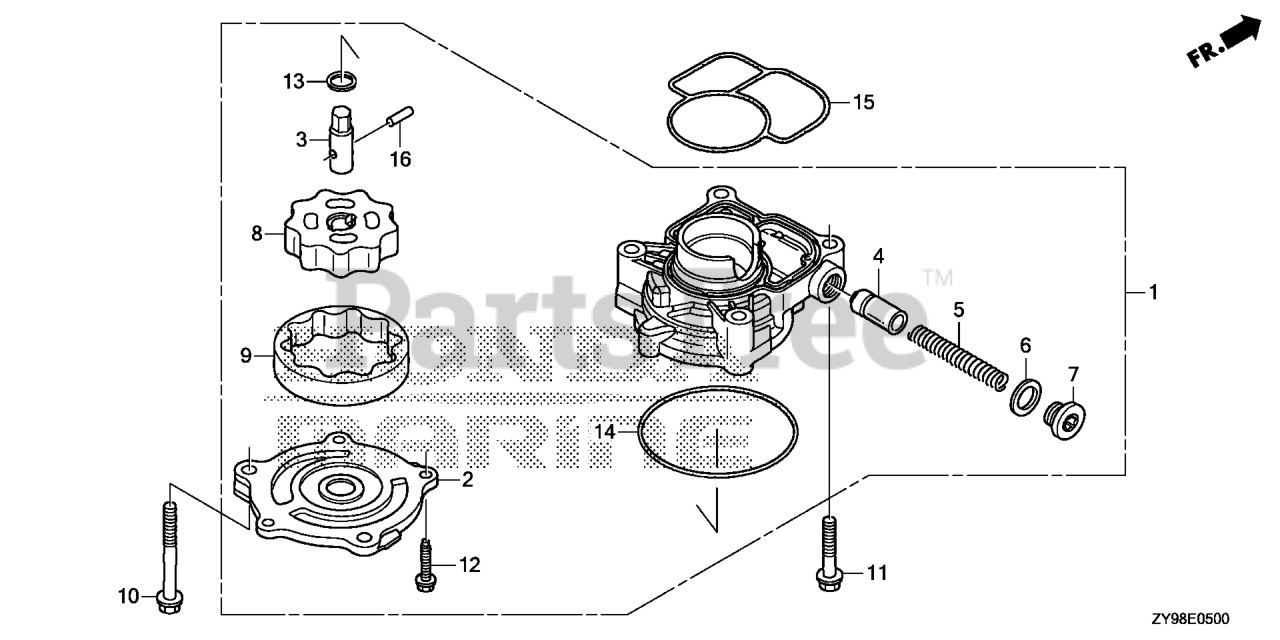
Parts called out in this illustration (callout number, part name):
1	PUMP ASSY., OIL
2	COVER, OIL PUMP
3	SHAFT, OIL PUMP
4	VALVE, RELIEF
5	SPRING, RELIEF VALVE
6	WASHER, SEALING (18MM)
7	BOLT, SEALING (18MM)
8	ROTOR (INNER)
9	ROTOR (OUTER)
10	BOLT, FLANGE (8X60)
11	BOLT, FLANGE (8X40)
12	BOLT, FLANGE (6X18) (CT200)
12	BOLT (6X18) (CT200)
13	WASHER, THRUST (12MM)
14	O-RING, PUMP COVER
15	O-RING, OIL PUMP
16	ROLLER (5X17.8)
